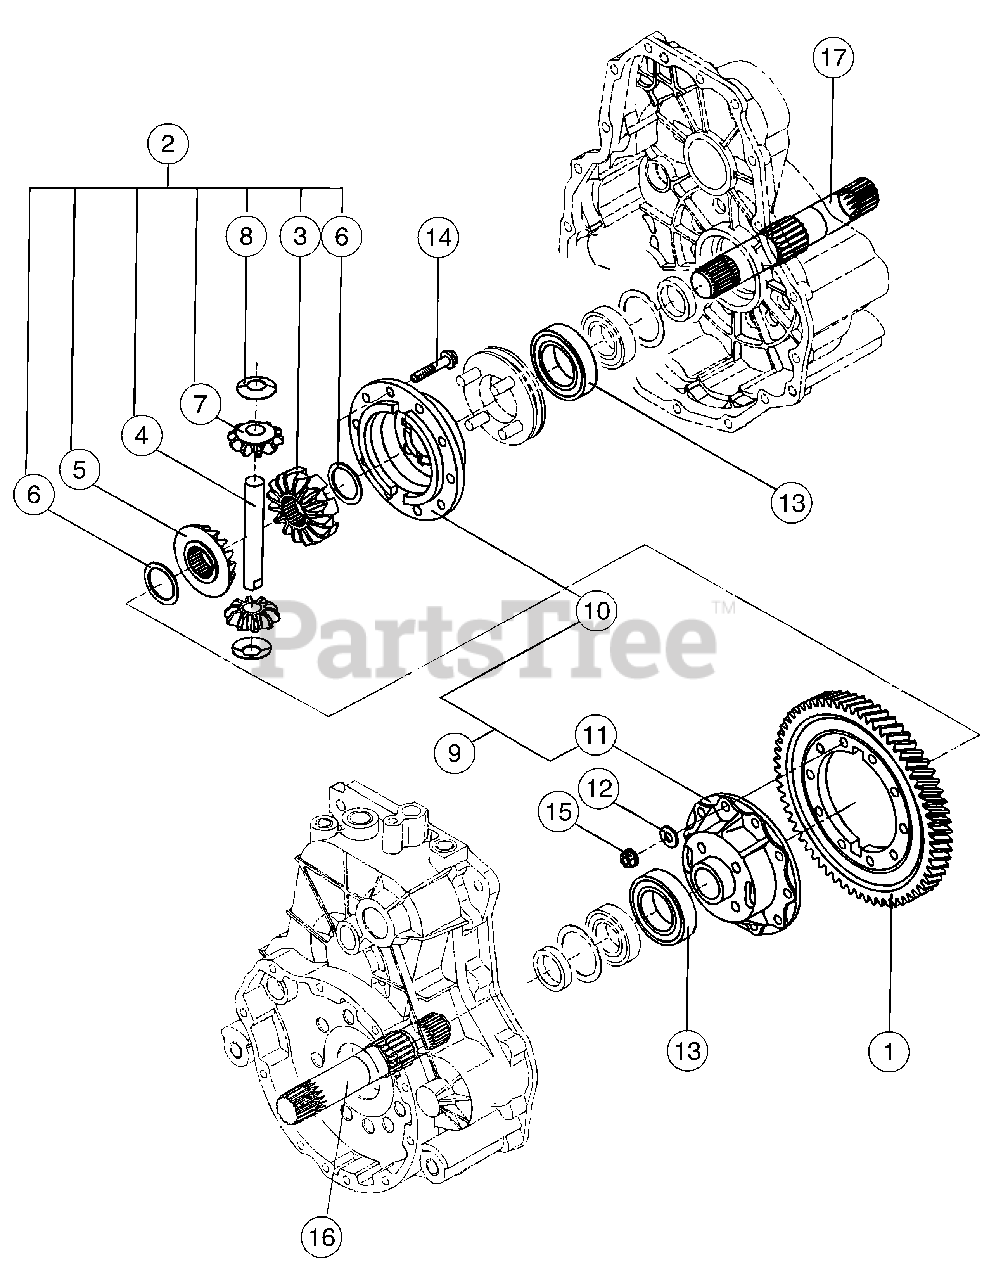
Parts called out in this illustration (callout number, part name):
1	Gear, 63H, Final
2	Differential, Gear Kit
3	Gear (RR, Differential)
4	Shaft, Differential Pinion
5	Differential Side Gear, RH
6	Washer, Differential Gear
7	Pinion, Differential
8	Washer, Differential Pinion
9	Differential, Case Kit
10	Case (R, Differential)
11	Case (L, Differential)
12	Washer, 8
13	Bearing, 6008
14	Bolt, 8 x 40
15	Nut, 8
